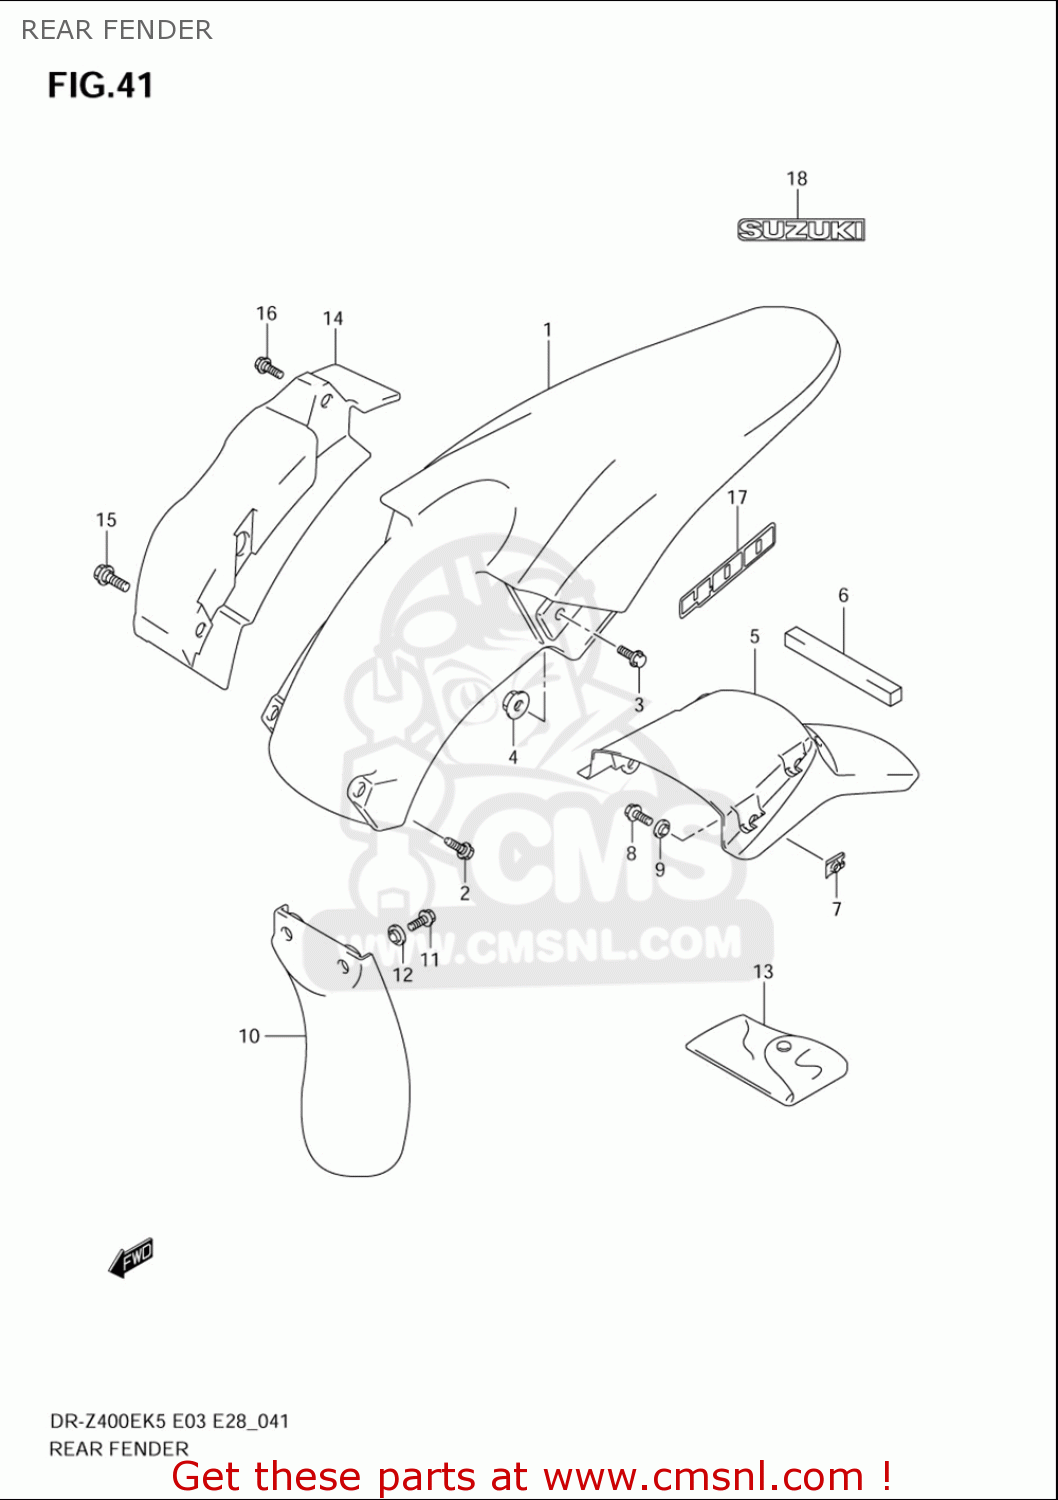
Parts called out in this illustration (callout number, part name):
1	FENDER,RR
2	BOLT(6X16)
3	BOLT(6X18)
4	NUT
5	EXTENSION,RR FENDER
6	CUSHION,RR EXTENSION
7	NUT
8	BOLT
9	WASHER (5X14X1)
10	MUDGUARD,RR FENDER FR
11	BOLT
12	WASHER
13	SPANNER,OPEN
14	MUDGUARD,RR FENDER,R
15	BOLT(6X18)
16	BOLT
17	EMBLEM,RR FENDER
18	EMBLEM,RR
